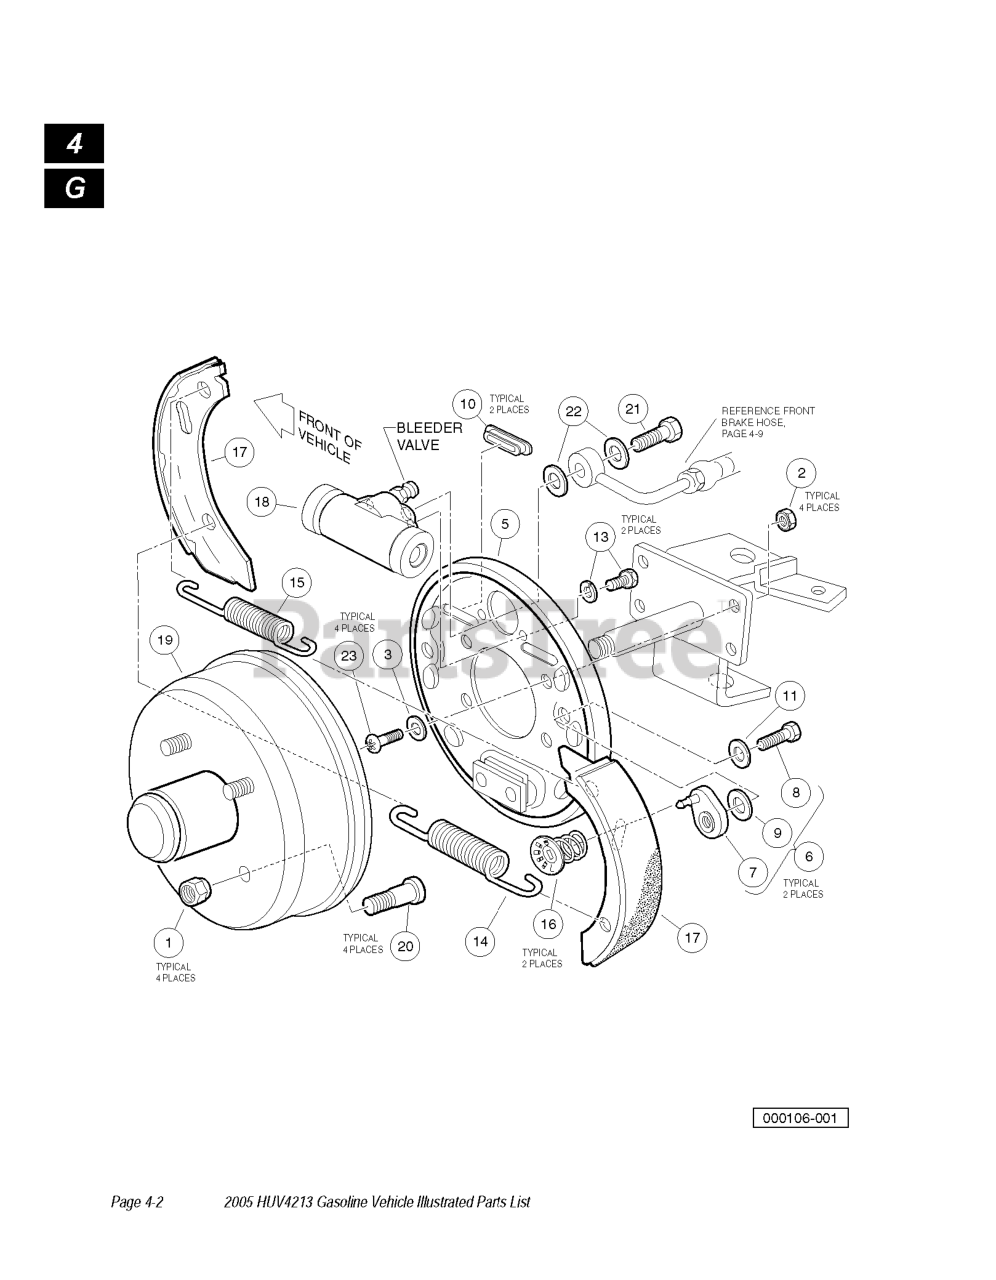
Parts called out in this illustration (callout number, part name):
1	NUT 1/2-20 LUG
3	WASHER, 5/16 HARDENED
4	FRONT BRAKE CLUSTER HYD
5	BACKING PLATE ASM
6	ADJUSTER KIT AXLE
8	BOLT, 1/4-28 UNF X .31 LG
10	DUST COVER
12	HARDWARE KIT - AXLE
13	BOLT, WHL CYL-M6 X 1 SELF LOCK
14	SPRING, SHOE TO SHOE - LOWER
15	SPRING, SHOE TO SHOE UPPER
16	SHOE HOLD DOWN
17	SHOE KIT - AXLE SET
18	WHEEL CYCL ASM .625 DIA
21	BANJO BOLT
22	COPPER WASHER
23	SCREW, 5/16-24 X 1.0 TORX HD
